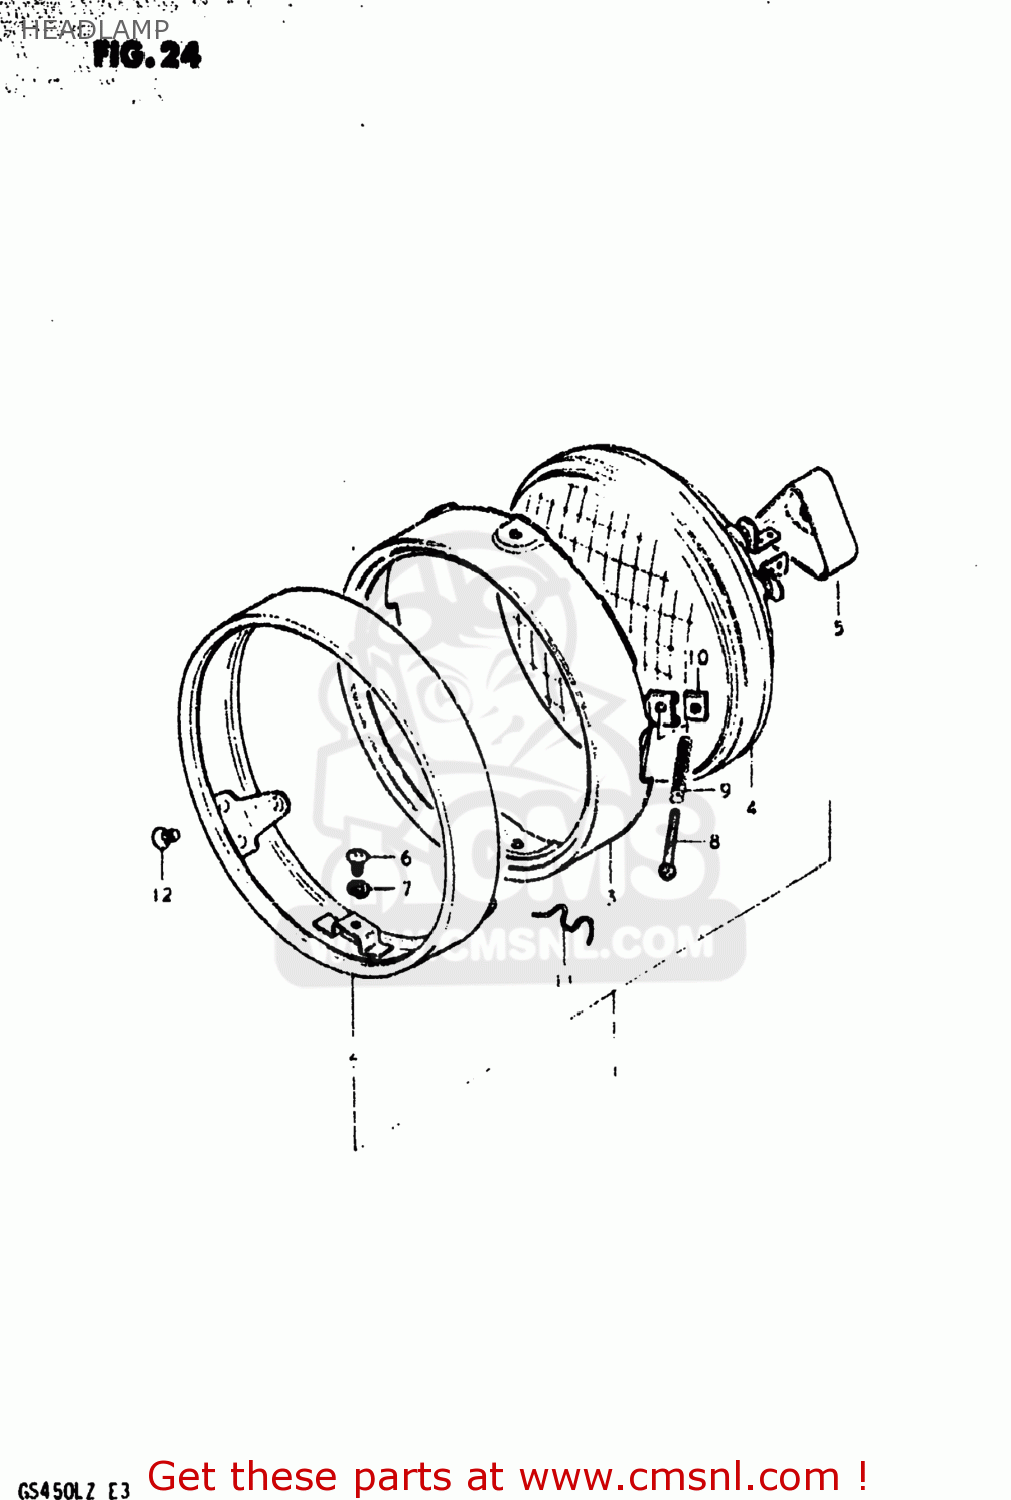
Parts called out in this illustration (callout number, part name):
1	LAMP ASSEMBLY,HEAD
2	RIM
3	RETAINER
4	LAMP UNIT
5	COVER
6	SCREW
7	LOCK WASHER
8	SCREW
9	SPRING
10	NUT
11	SPRING,HEAD LAMP UNIT
12	SCREW(5X12)
